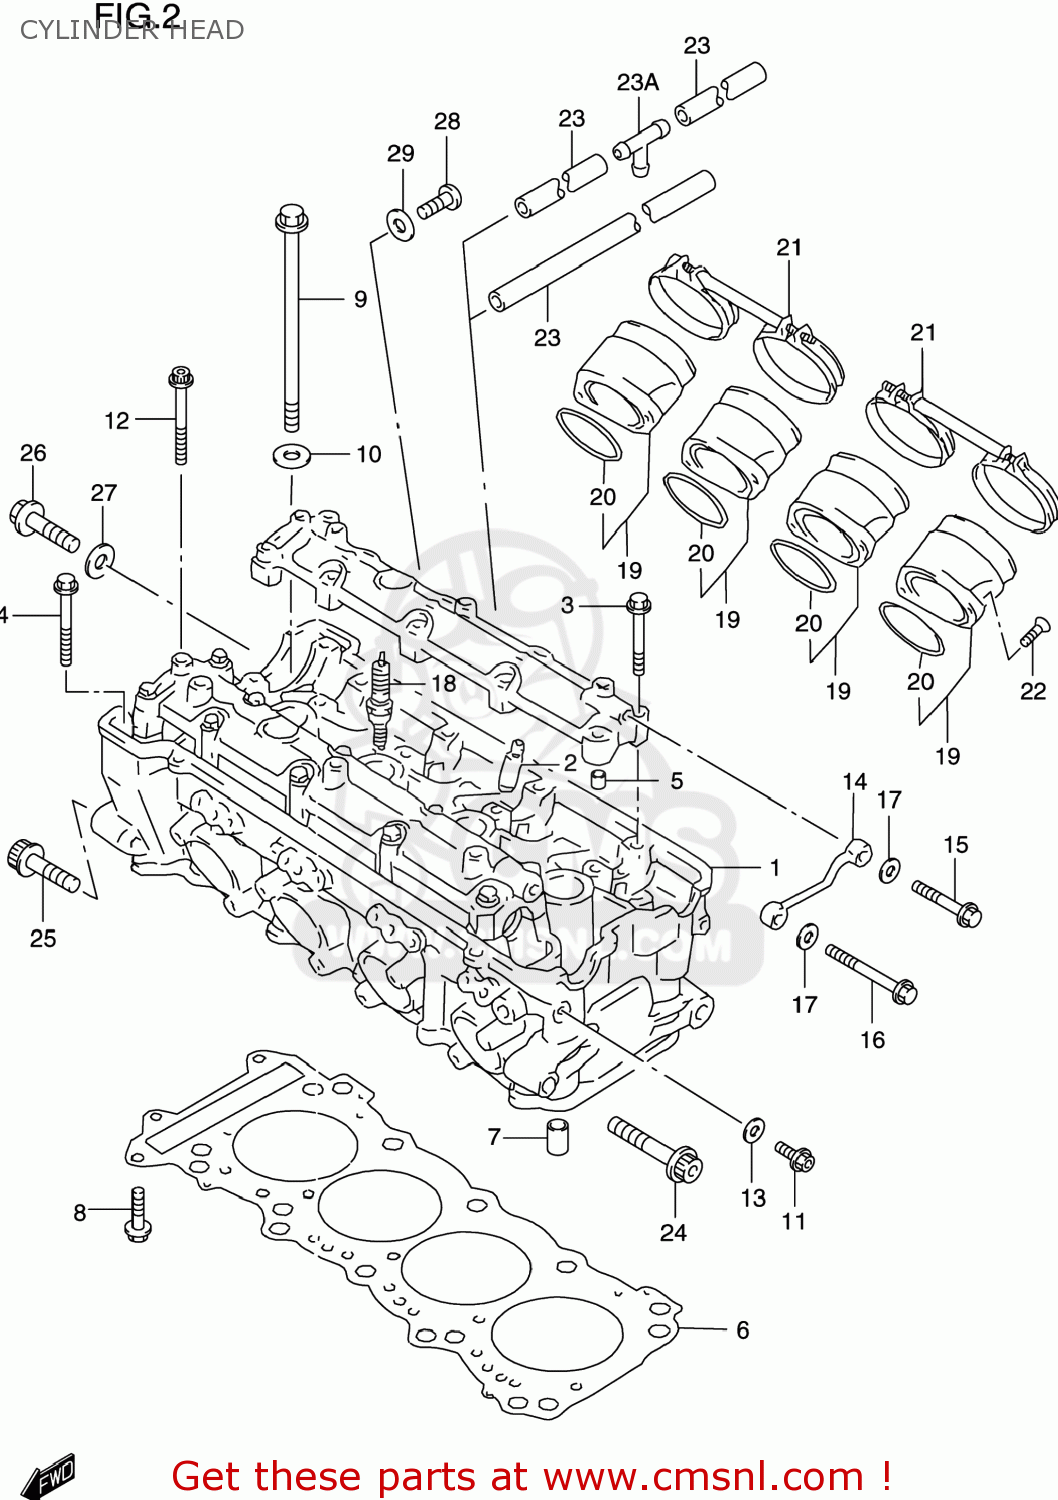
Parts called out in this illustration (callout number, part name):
1	HEAD SET,CYLINDER
2	GUIDE,VALVE
3	BOLT(6X39)
4	BOLT(6X45)
5	PIN(6.2X8X16)
6	GASKET,CYLINDER HEAD
7	PIN
8	BOLT
9	BOLT(10X160)
10	WASHER(10.5X19X2)
11	BOLT
12	BOLT,CYL.OIL P
13	GASKET(5.8X13X1.2) (NAS)
14	PIPE,CYLINDER HEAD OIL
15	BOLT
16	BOLT (6X45)
17	WASHER
18	PLUG,SPARK(CR8E)
19	PIPE ASSY,INTAKE
20	O RING(D:2.4,ID:44)
21	CLAMP COMP,INTAKE PIPE
22	SCREW
23	HOSE(5X10X600)
23A	JOINT,3 WAY
24	BOLT
25	BOLT
26	BOLT,CYL HEAD SIDE FACE
27	WASHER,HEAD COVER
28	SCREW
29	GASKET(6.2X11X1).2 (NAS)
